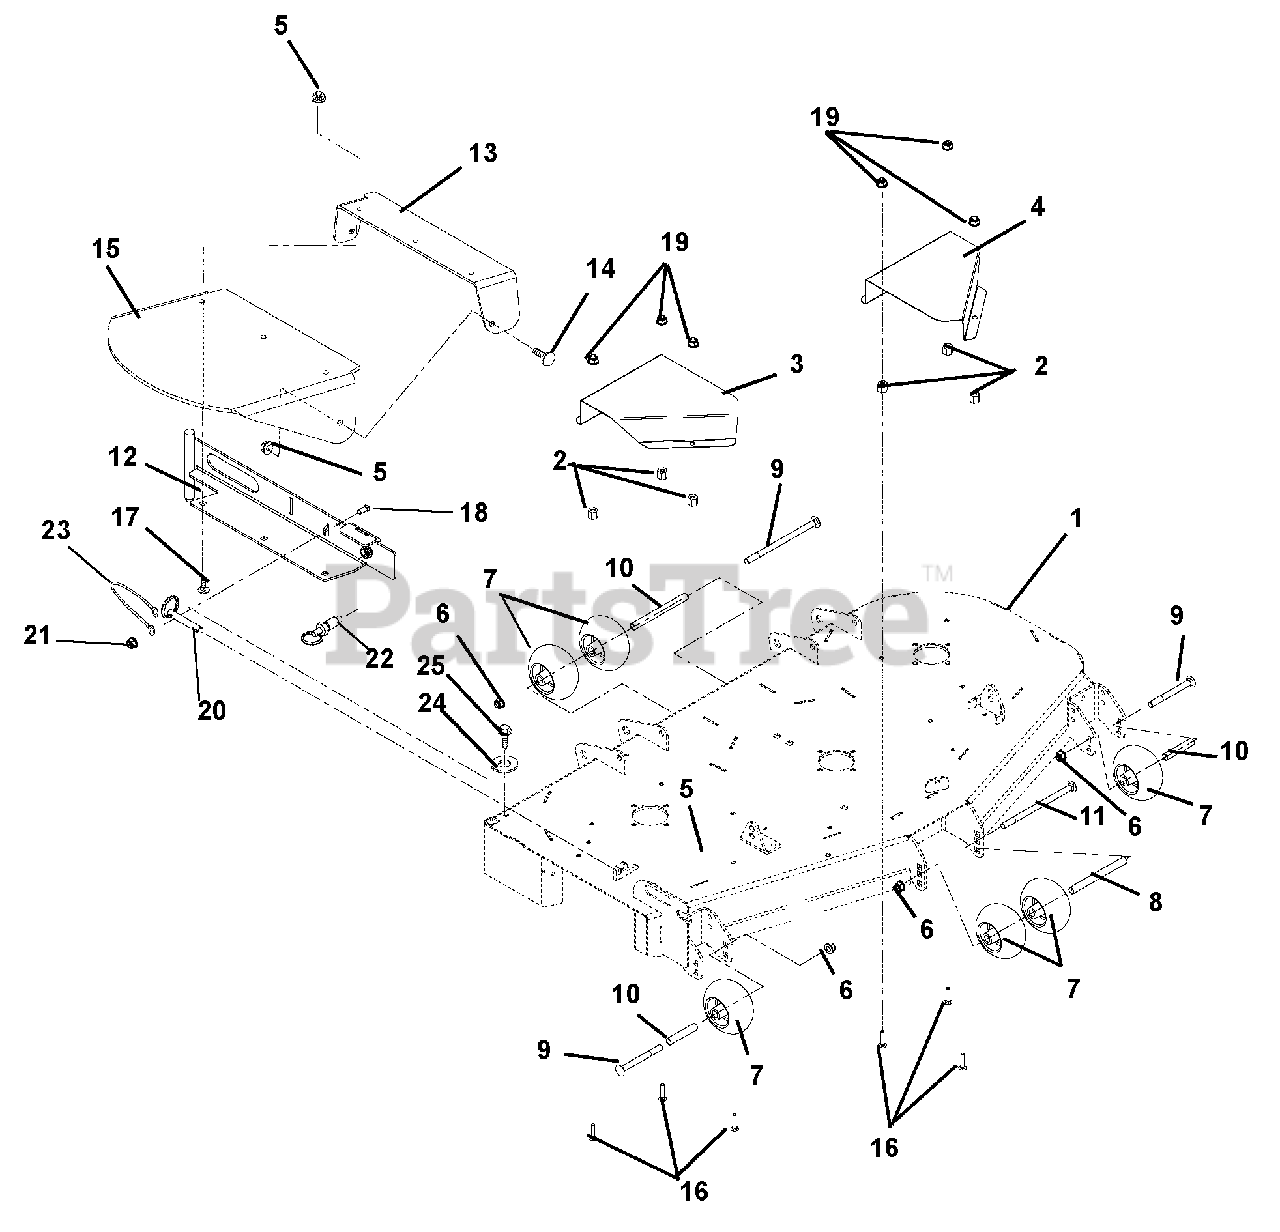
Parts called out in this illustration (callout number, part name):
1	Weldment, 60" Side Discharge Deck (070)
1	Weldment, 52" Side Discharge Deck (069)
1	48" Side Discharge Deck Weldment (068)
2	Nut, Heavy Hex .38-16
3	Guard, 60" Right Hand Spindle Sheave (070)
3	Guard, 48"-52" Right Hand Spindle Sheave Guard (068, 069)
4	Guard, 60" Left Hand Spindle Sheave (070)
4	Guard, 44"-52" Left Hand Spindle Sheave (068, 069)
5	Nut, .38-16 Nyloc Flange
6	Nut .50-13 Nyloc Flange
7	Anti-Scalp Wheel (068)
7	Anti-Scalp Wheel (069, 070)
8	Spacer (068)
8	Spacer (069, 070)
9	Bolt, Round Head Square Neck .50-13 x 5.00 (068)
9	Bolt, Round Head Square Neck .50-13 x 5.00 (069, 070)
10	Spacer, .510 x .625 x 3.35 (068)
10	Spacer, .510 x .625 x 3.35 (069, 070)
11	Bolt, Round Head Square Neck .50-13 x 8.50 (068)
11	Bolt, Round Head Square Neck .50-13 x 8.50 (069, 070)
12	Weldment, 52"-60" Discharge Chute Mounting (070)
12	Weldment, 48" Discharge Chute Mounting (068)
13	Rubber Discharge Chute Support
14	Bolt, Round Head Square Neck .38-16 x 1.00 Grade 5
15	Chute, Rubber Discharge
16	Bolt, Hex .38-16 x 1.25 Grade 5
17	Bolt, Round Head Square Neck .38-16 x 1.25 Grade 5
18	Bolt, Hex .25-20 x .75 Grade 5
19	Nut, Flange .375-16
20	Pin, Spring Ball .375OD x 1.50
21	Nut, Locking-Top-Flange .25-20
22	Pull Pin
23	Cable, 6.00 Lanyard - Nylon
24	Bumper, Recessed 1.50 x .63 W/.31 Thru Hole
25	Screw, Tapping .31-18 x .75 Hex Washer Head
